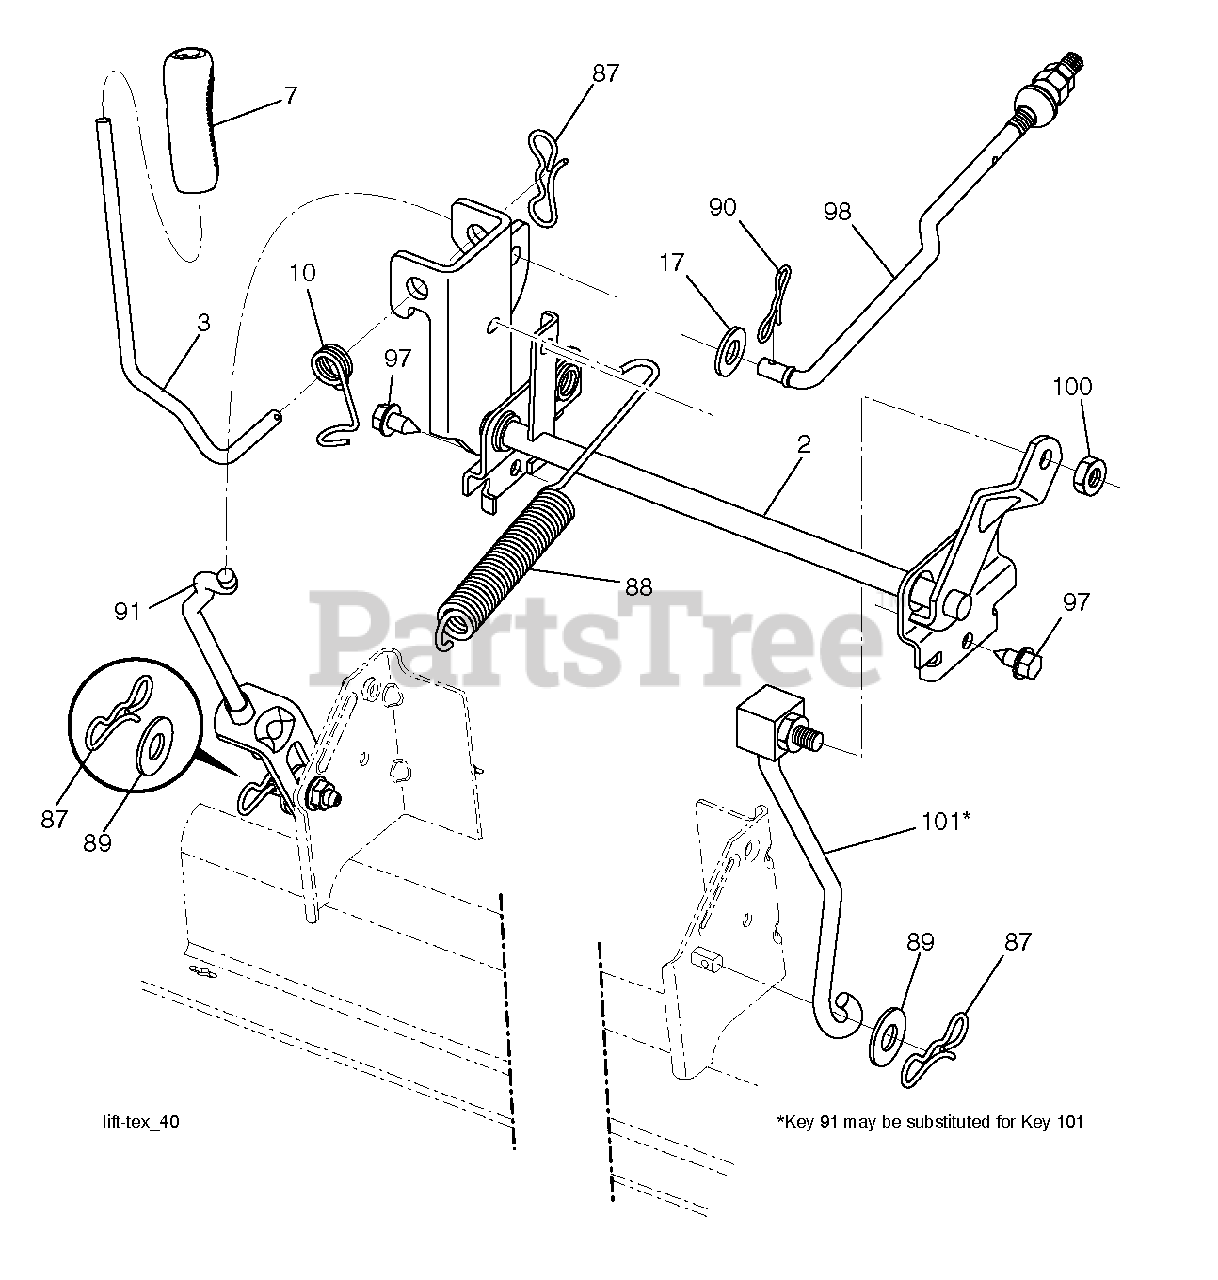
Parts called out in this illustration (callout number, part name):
2	SHAFT.ASM.CROSS.LIFT
3	LEVER.LIFT.HANDLE.LT
7	GRIP.HANDLE.LIFT.PVC.BLACK
10	SPRING.TORSION.LIFT.HANDLE
17	WASHER
87	PIN.COTTER.7/16.BOW TI.
88	SPRING.LIFT.ASSIST
89	WASHER.CLEAR.ZINC
90	PIN.COTTER.5/16.BOW TI
91	LINK.ASM.LIFT.REAR
97	SCREW, 3/8-16X3/4
98	LINK.ASM.SUSP.FRONT.MW
100	LOCKNUT
101	LINK.ASM.LIFT.FIXE.38/42/46"
